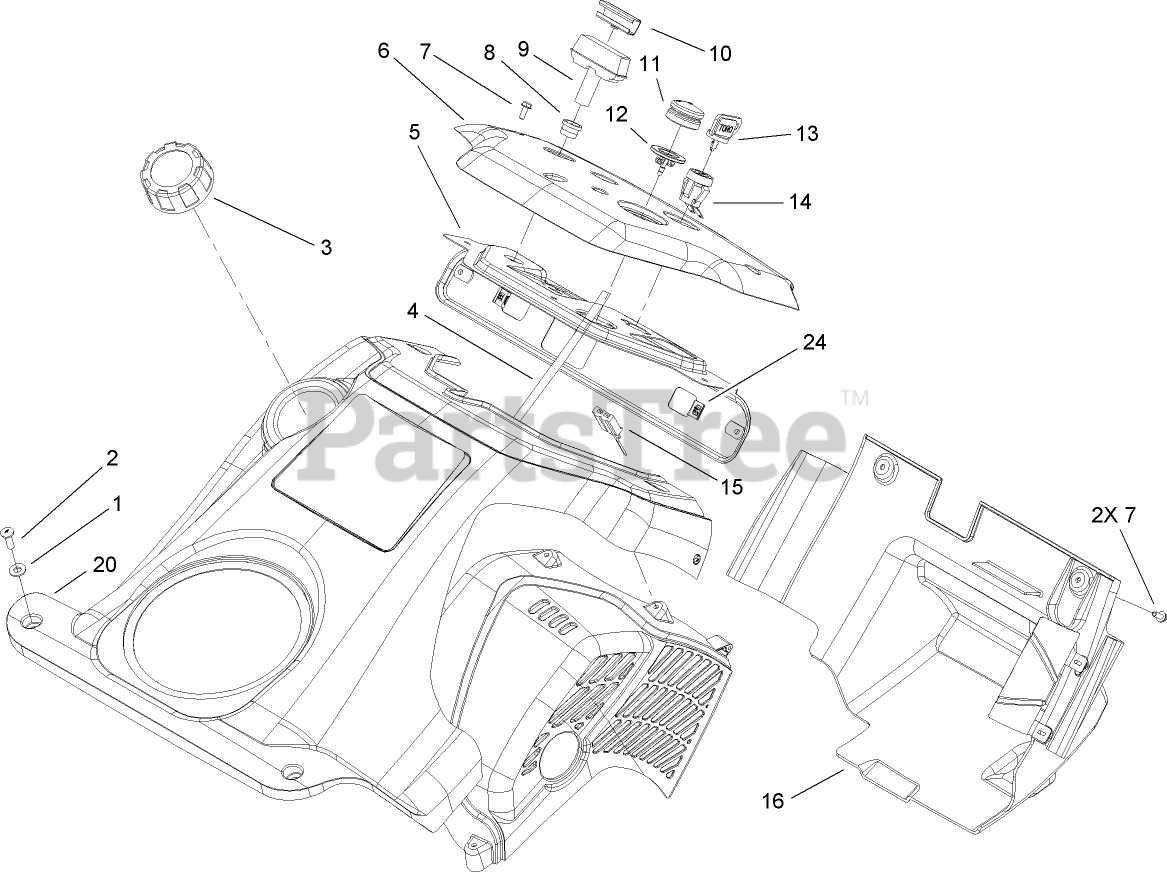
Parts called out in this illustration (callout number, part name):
1	WASHER-FLAT
2	SCREW-PPH
3	GAS CAP ASM
4	HOSE-PRIMER
5	PANEL-SUPPORT, CONTROL
6	PANEL-CONTROL
7	SCREW-HWH
8	GUIDE-ROPE, STARTER
10	CLIP-STARTER
11	BULB-PRIMER
12	BODY-PRIMER
13	KEY-IGNITION
14	SWITCH
15	CONNECTOR-BODY
16	LOWER SHROUD/BAFFLE ASM
24	NUT-SPEED
